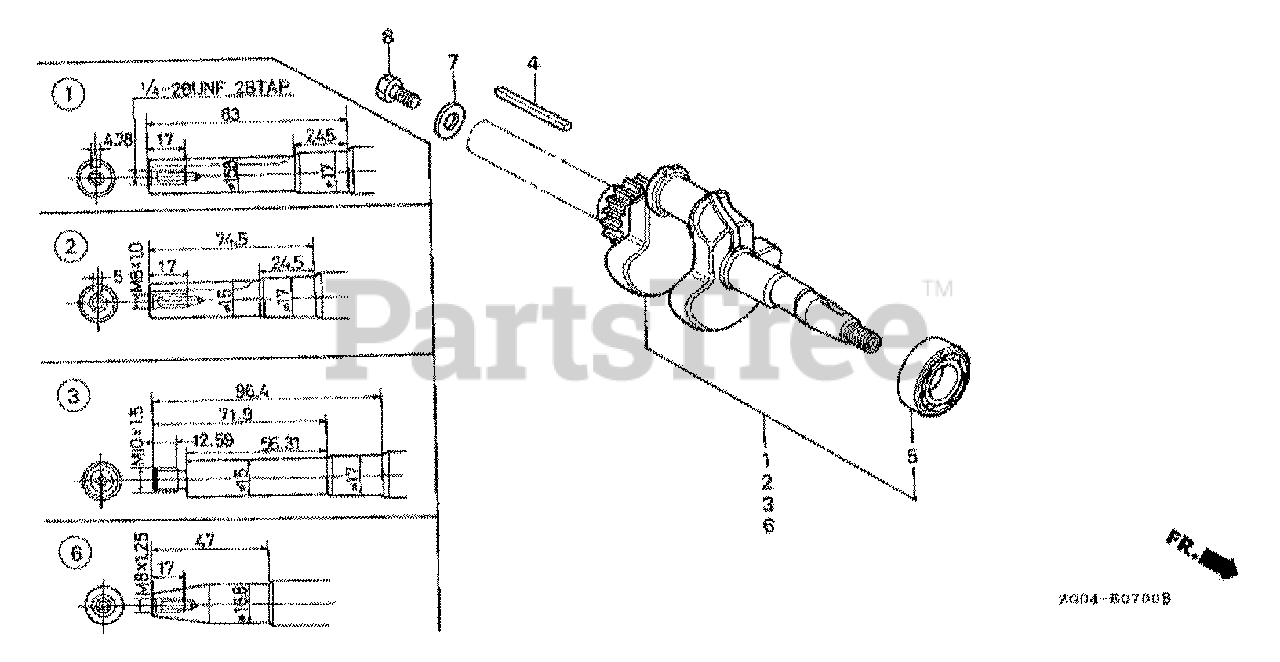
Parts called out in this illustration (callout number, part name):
1	CRANKSHAFT (Q-TYPE)
4	KEY (4.78X4.78X38)
5	BEARING, RADIAL BALL (6203)
